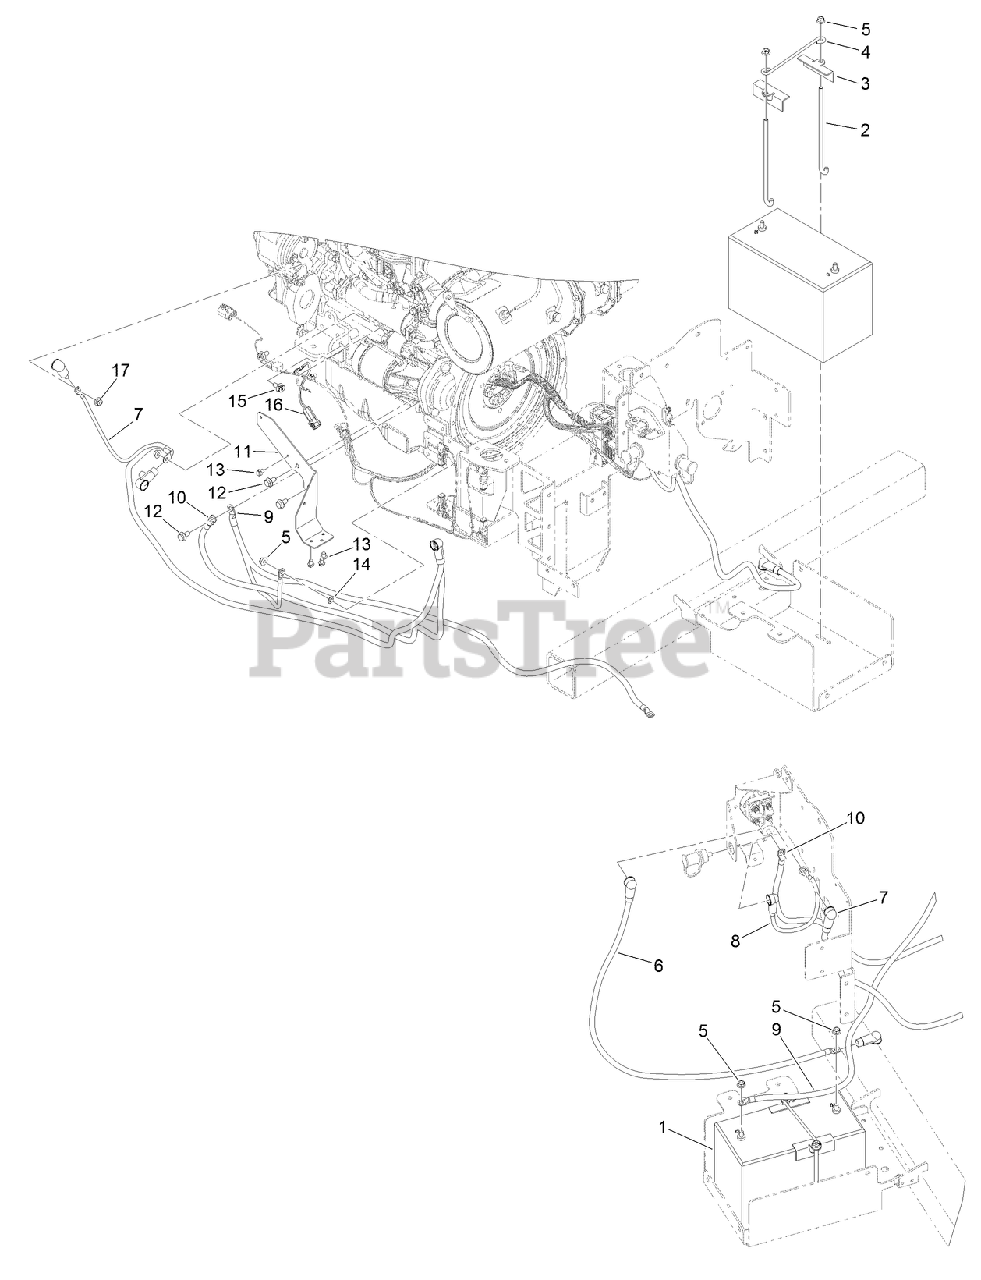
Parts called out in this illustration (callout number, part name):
1	BATTERY (1000CCA, WET)
2	BOLT-HOLDDOWN, BATTERY
3	ANGLE-HOLDDOWN, BATTERY
4	BRACKET-HOLDDOWN, BATTERY
5	NUT-HF, NI
6	CABLE-BATTERY, POSITIVE
7	CABLE-BATTERY, POSITIVE
8	CABLE-BATTERY, POSITIVE
9	CABLE-BATTERY, NEGATIVE
10	CABLE-BATTERY, NEGATIVE
11	PLATE-ELECTRICAL, ENGINE
12	SCREW-HHF
13	CLIP-TIE
14	WASHER-LOCK
15	CLIP-TREE (W/TIE)
16	HARNESS-WIRE, FUSIBLE LINK
17	NUT-HF
